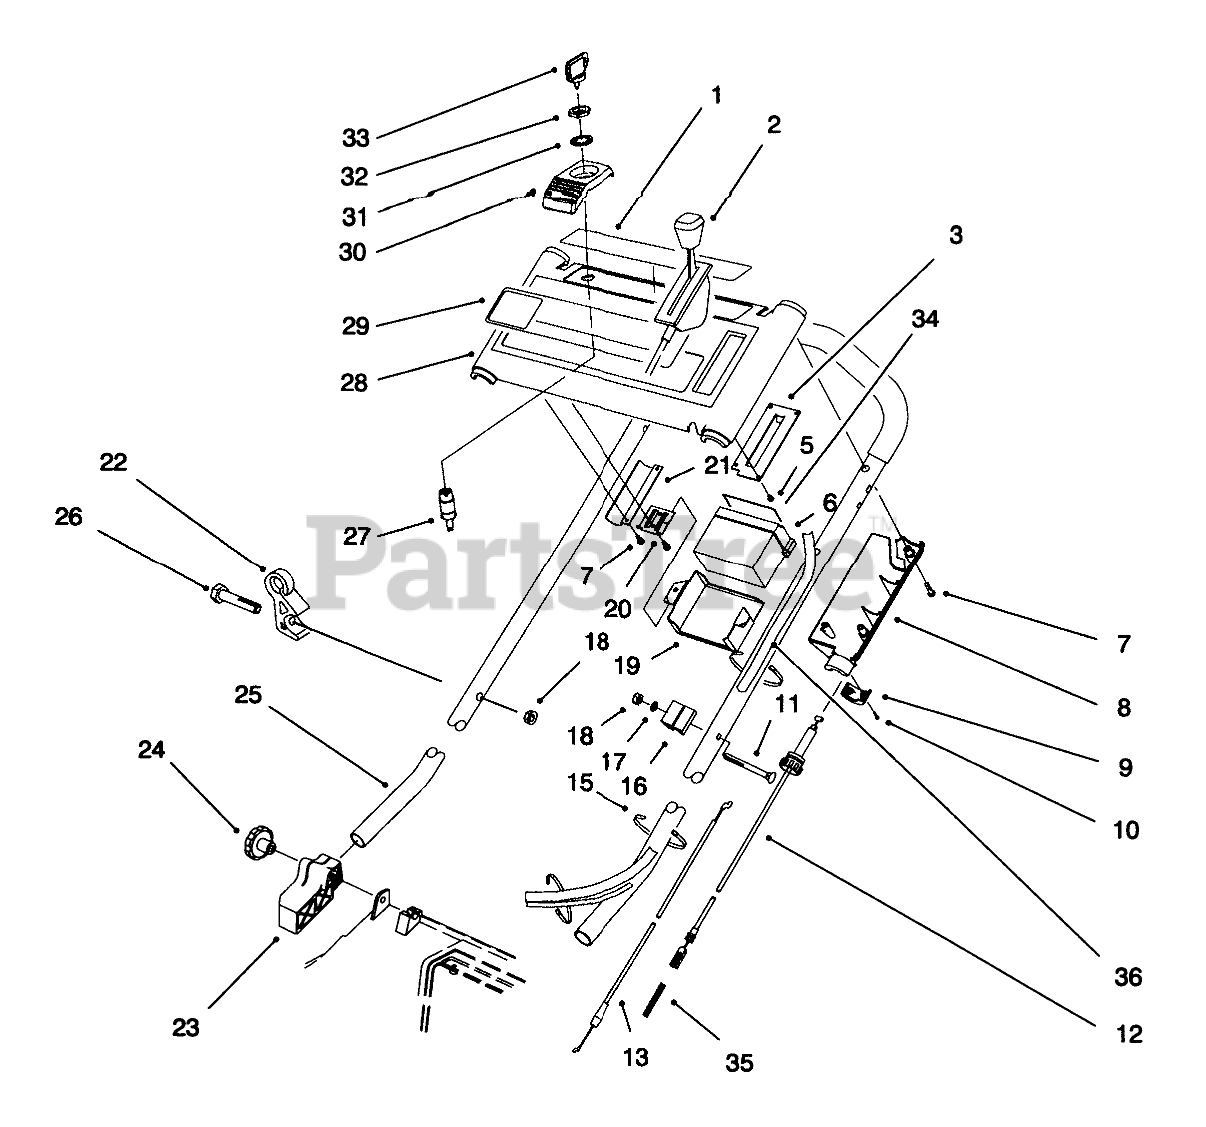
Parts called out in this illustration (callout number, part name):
1	DECAL - CONTROL PANEL
2	CONTROL - THROTTLE
3	THROTTLE PLATE
5	#6-19X.25 PLASK FORM SC
6	BATTERY ASSEMBLY
7	SCREW-PPH, PLASTITE
8	COVER-THROTTLE, LEVER
9	LOWER THROTTLE CAP
10	#4-14X.62 PLASTITE SCW
11	SCREW-HANDLE
12	ASM - TRACTION CABLE
13	CABLE - BRAKE
15	TIE-CABLE
16	SUPPORT-CABLE
17	WASHER-FLAT
18	NUT-LOCK, NI
19	Retainer-Battery
20	BATTERY BRACKET
21	Bracket-Panel
22	GUIDE - ROPE
23	MOUNT-HANDLE, RH
25	Handle
26	.250-20X1.625 HH SCREW
27	Switch-Starter (Incl. Ref. #31 & 32)
28	Panel-Control (Incl. Ref. #1 & 29)
29	DECAL - PANEL KEY
30	IGNITION SWITCH BRACKET
31	WASHER-TOOTH, INTERNAL
32	NUT-HH
33	KEY-IGNITION
34	DECAL-BATTERY
35	SPRING-COMPRESSION
36	WIRE HARNESS
